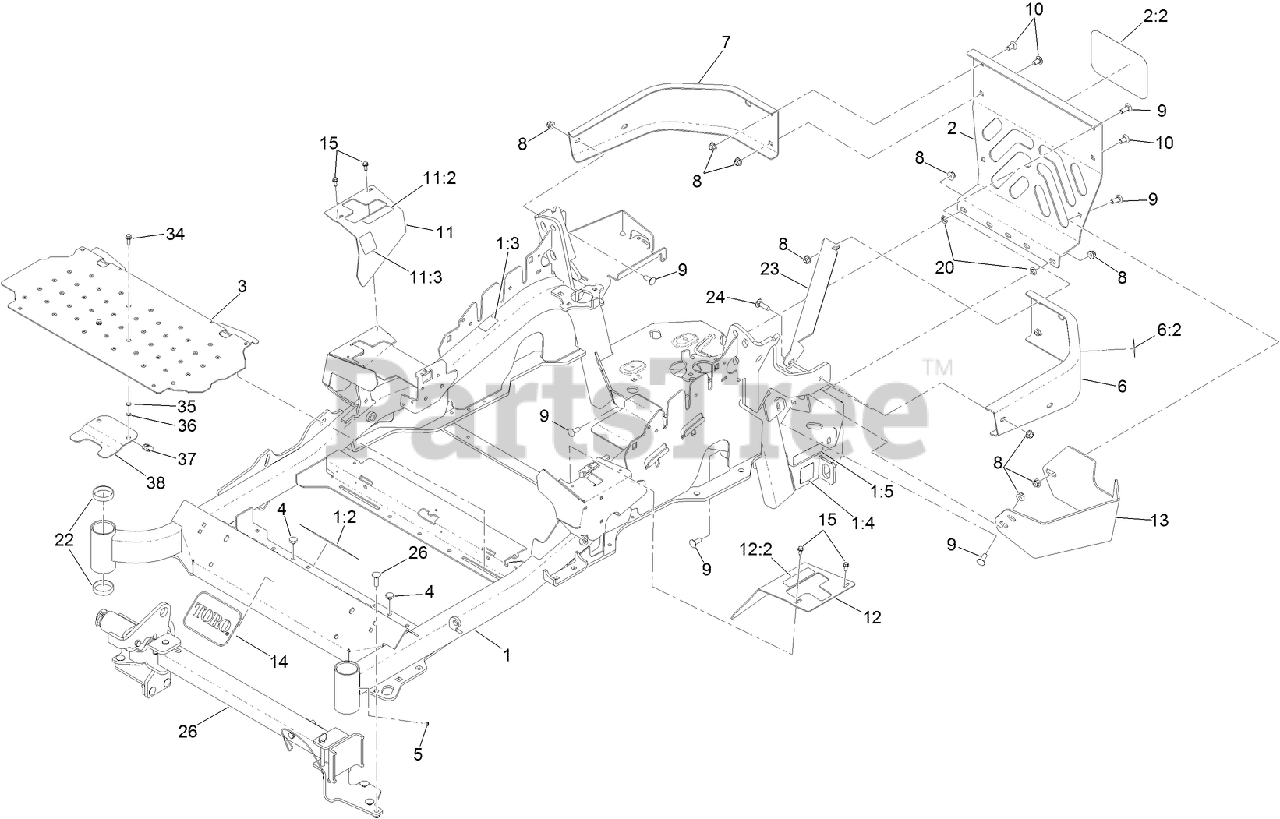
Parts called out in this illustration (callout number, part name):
1	MAINFRAME ASM
1:2	DECAL-DANGER
1:3	DECAL-WARNING
1:4	DECAL-HAZARD, PINCHED FINGER
1:5	DECAL-ARRESTOR, SPARK
2	REAR GUARD ASM
2:2	DECAL
3	FLOORPAN
4	BUMPER
6	LH BUMPER ASM
6:2	DECAL-WARNING
7	BUMPER-RH
8	NUT-HF, NI
9	SCREW-CARR
10	SCREW-CARR
11	RH MOTION CONTROL COVER ASM
11:2	DECAL-CONTROL, MOTION
11:3	DECAL-PARK BRAKE, CE
12	LH MOTION CONTROL COVER ASM
12:2	DECAL-CONTROL, MOTION
13	GUARD-MUFFLER
14	DECAL
15	SCREW-HWH
20	NUT-PUSH
22	CUP-BEARING
24	BOLT-CARR
26	Z STAND ASM
34	SCREW-HH
35	WASHER-FLAT
36	NUT-RETAINER
38	ADAPTER-CAPTIVE
